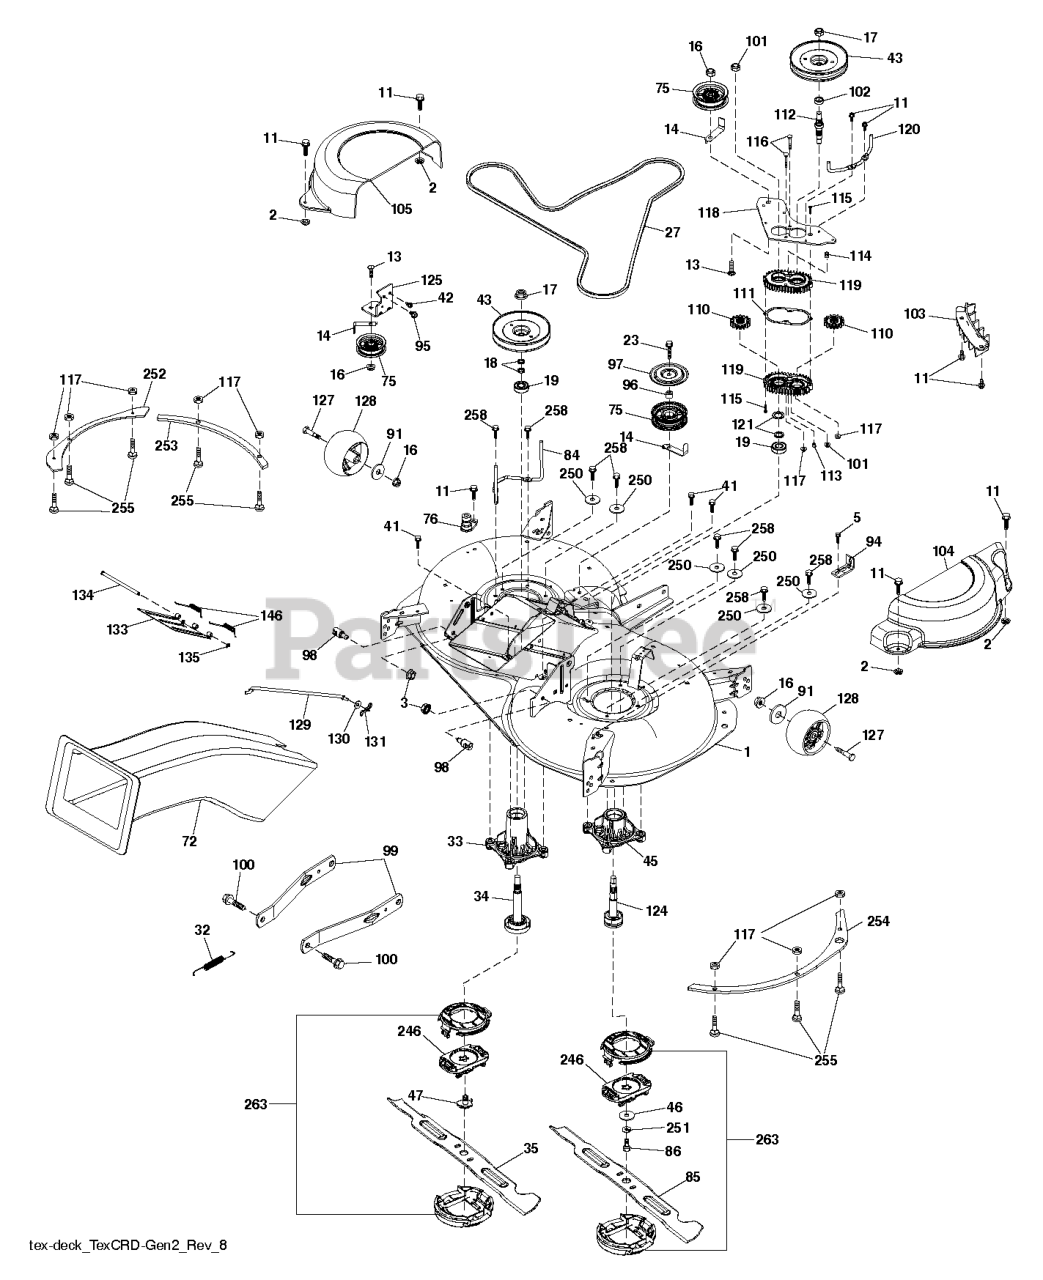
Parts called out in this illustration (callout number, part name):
1	DECK.SVC.WLDT.97EL.TCRD.EZ.498
2	PALNUT 1/4
3	NUT LOCK HEX FLANGE 5/16-18
5	BOLT.5/16HEX.WHS.HD
11	SCREW.1/4-20X5/8
13	BOLT.3/8-16X1.50
14	KEEPER, BELT IDLER
16	NUT LOCK FLG 3/8-16 UNC
17	NUT.FLANGE.LOCK.TOP
18	WASHER.SPACER.MANDREL
23	SCREW LT
27	BELT 97CM ELECTRIC
32	SPRING 107CM & 97CM ELECTRIC D
33	RP.HOUSG.MAND.REV.TALL.N/GRS
34	RP.SAFT ASM.REV.TALL.N/GREASE
35	BLADE.REVOLUTION.97CM.LHS
41	BOLT.HEX.WASHR.HED.313-18X1.19
42	SCREW
43	PULLEY.MANDREL.5.0.PD.38"
45	RP HOUSING.MANDREL.REV.REVS.
46	3/8 FLAT WASHER
47	SCREW.SEMS.7/16-20X1.HEX.HEAD
72	RP.CHUTE 107/97 TEX GENII
75	FLAT IDLER PULLEY
76	PORT.WASHOUT
84	BELT KEEPER.MANDREL.38"COATED
85	BLADE.REVOLUTION.97CM.RHS
86	BOLT.3/8-24X1.25GR8. LHTHRD
91	WASHER
94	BRKT.CLUTCH.CABLE
95	SCREW, 3/8-16X3/4
96	SPACER
97	PROTECTOR
98	STUD.FASTNER.W/ANTI-ROTATE
99	ARM.SUSPENSION.MOWER.R
100	BOLT.SHOULDER
101	NUT.CROWNLOCK.9/16 -18.UNC
102	SPACER BEARING
103	GUARD GUARD FRONT VENT
104	97.CRD.RH.MANDREL.COVER
105	MANDREL MANDREL COVER LH
110	CRD.SPUR.GEAR
111	GASKET GASKET GEARCASE
112	SHAFT SHAFT. CRD GEARCASE ADAP
113	PLUG PLUG OIL
114	VALVE VALVE RELIEF
115	SCREW
116	BOLT.CARIGE.SS.1/4-20X1.75GR5
117	NUT T
118	ARM ARM CLUTCHING
119	GEARCASE GEARCASE SUBASM
120	BRACKET KEEPER BELT RH
121	WASHER WASHER
124	SUB.ASM.REVERSE.THREAD.REV
125	BRACKET
127	BOLT.SHOULDER.3/8-16X3-5/8.
128	RP WHEEL. GUAGE RALLY
129	ROD ROD. SWAY CRD GEN II
130	WASHER
131	PIN.COTTER.5/16.BOW TI
133	DOOR
134	PIN PIN.HINGE
135	E-RING.5/16"
146	SPRING SPRING: EZ MULCH DOOR
246	HOLDER.BLADE.REVOLUTION
251	LOCKWASHER
252	PLATE.REINFORCEMENT.X431
253	PLATE.REINFORCEMENT.LHS.X431
254	PLATE.REINFORCEMENT.LHS.X431
255	RHSNB, 1/4-20 X 1, GR5
258	BOLT.HEX.WASHR.HED.313-18X1.19
263	CAP.REVOLUTION ASM
